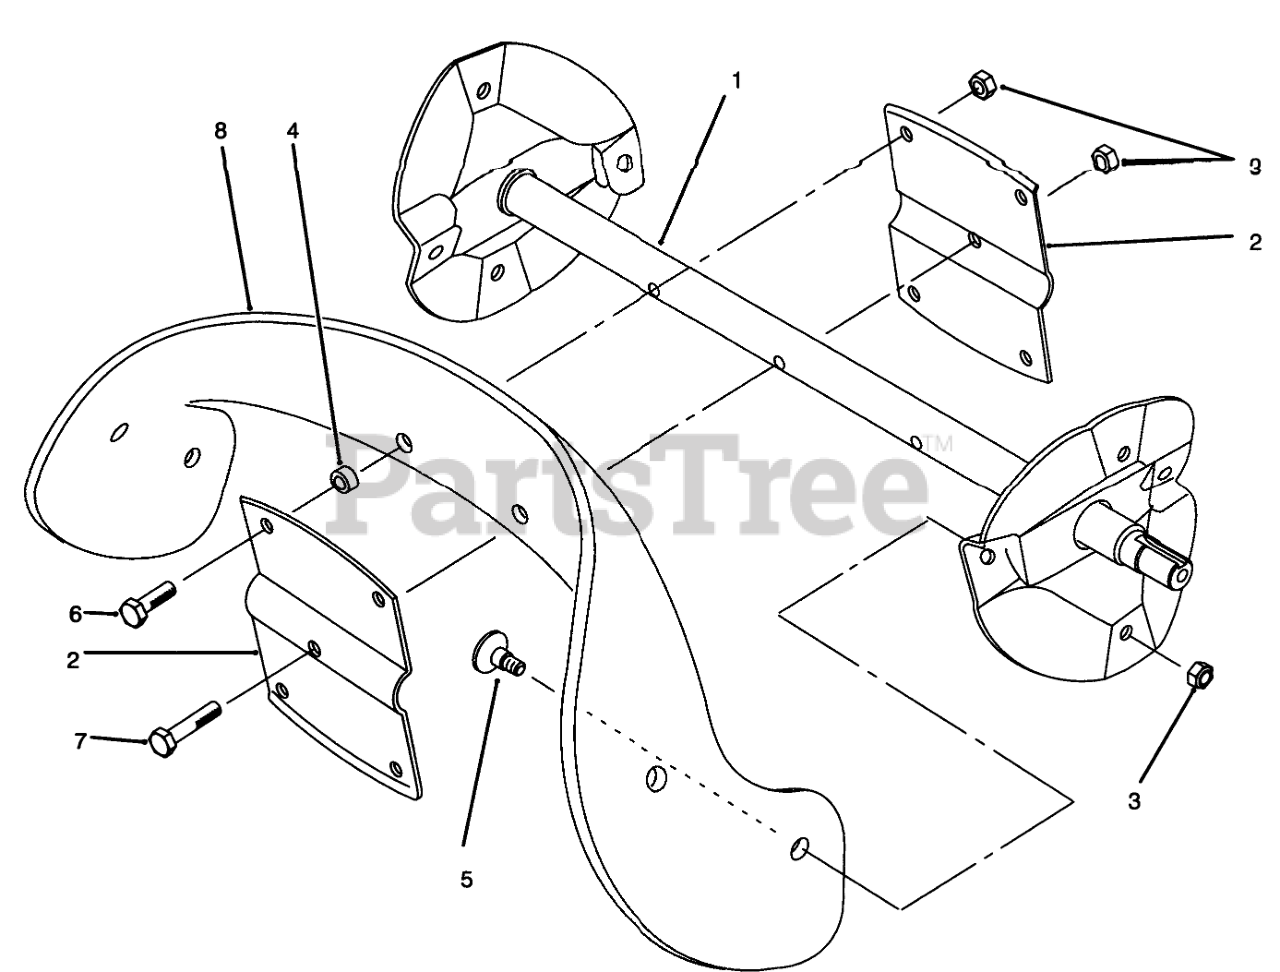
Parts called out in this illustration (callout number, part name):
1	Wa-Rotor
2	Rotor
3	NUT-LOCK, NI
4	SPACER-BLADE, ROTOR
5	SCREW
6	SCREW-HH
7	SCREW-HH
8	Blade-Rotor
